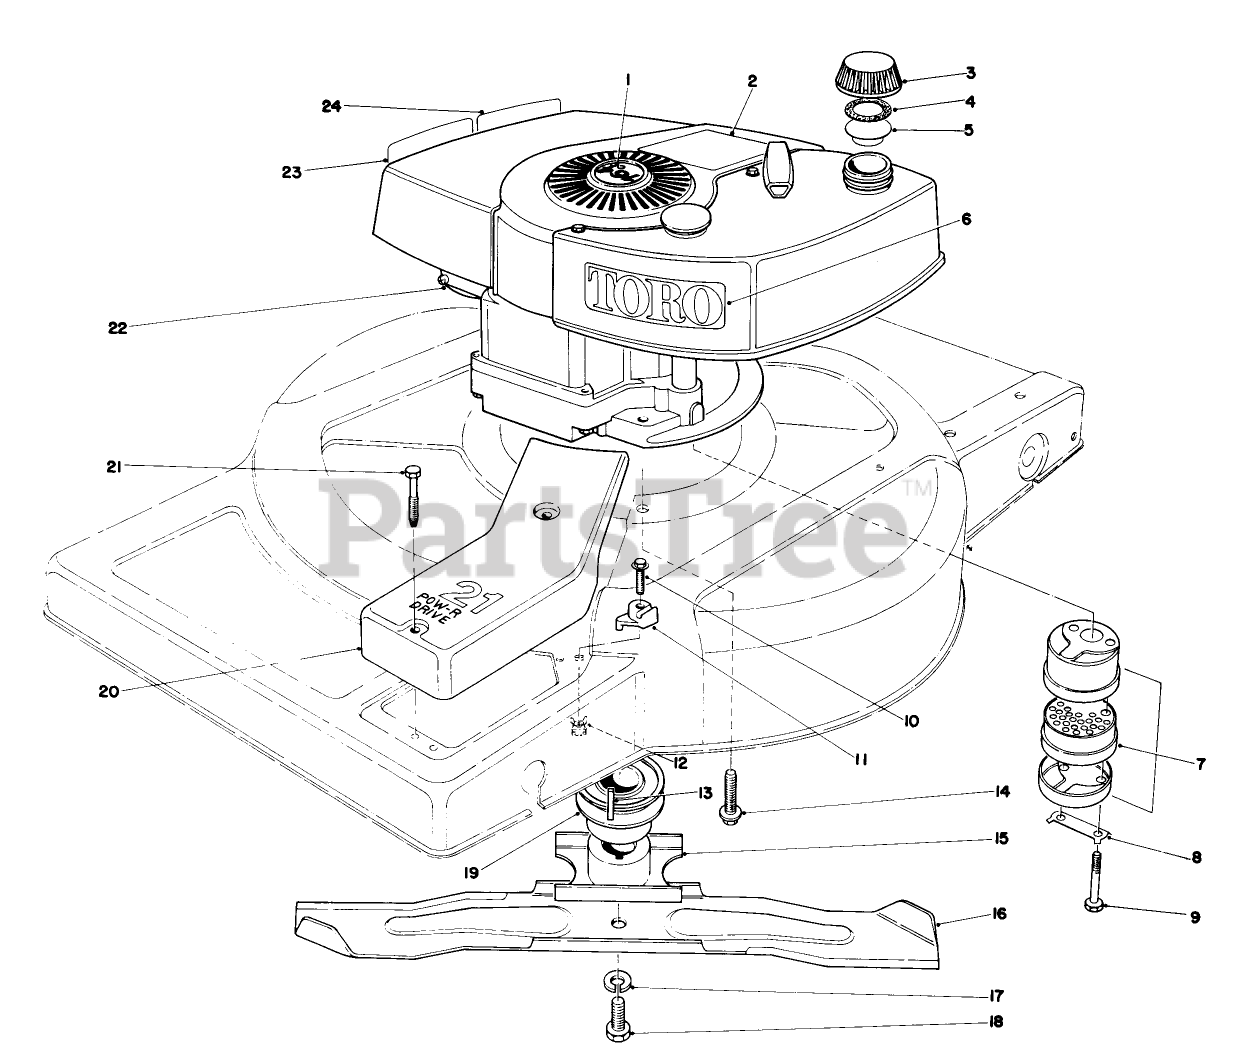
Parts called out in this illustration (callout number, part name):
1	Plug Button
2	Decal Lockout
3	Gas Cap (Incl. Ref. #4 & 5)
4	GASKET
5	GAS CAP BAFFLE
6	Decal Toro
7	Muffler Assy. (Incl. Ref. #8 & 9)
8	CLIP - LOCKING
9	SCREW-HH
11	CABLE BOSS
12	SPEED NUT
13	KEY-SQUARE
14	SCREW-HWHTF
15	BLADE RETAINER WA(BLACK)
16	Blade
17	WASHER-LOCK
18	BLADE SCREW
19	Pulley
20	COVER BELT
21	SCREW-HHFTF
22	Engine
23	Decal-Maintenan
24	Decal Maintenance
